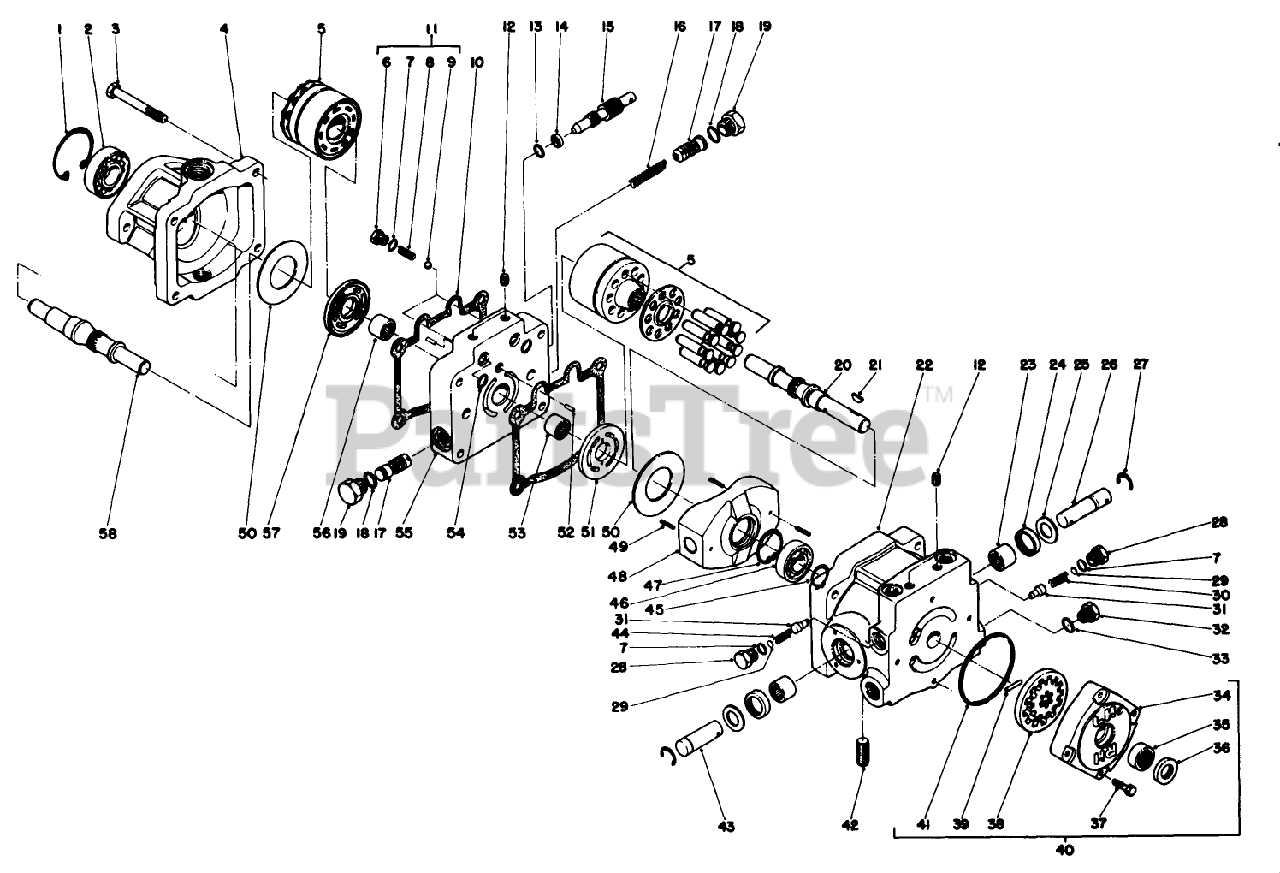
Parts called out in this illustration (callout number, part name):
1	RING-SNAP
2	BEARING
3	SCREW-HH
4	Motor Housing
5	CYLINDER BLOCK KIT
6	PLUG-VALVE, CHECK
7	O-RING
8	SPRING-VALVE
10	GASKET
11	Check Valve Kit (Incl. Ref.#6-9)
12	PLUG-PIPE
13	O-RING
14	RING-BACK UP
15	By Pass Valve
16	SPRING-VALVE
17	VALVE ASM
18	O-RING
19	PLUG-HYD, HH
20	Pump Shaft
21	KEY-WOODRUFF
22	PUMP HSG
23	BEARING-NEEDLE
24	SEAL-LIP
25	WASHER-FLAT
26	SHAFT-TRUNNION
27	RING-RETAINING
28	PLUG-HH
29	PACK-SHIM
30	SPRING-VALVE
31	Cone-Relief Valve
32	PLUG-HH
33	O-RING
34	HOUSING-PUMP, CHARGE
35	NEEDLE BRG
36	SEAL-OIL
37	Screw
38	Gerotor ASM
39	PIN-STRAIGHT, HEADLESS
40	Charge Pump (Incl. Ref.#34-39 & 41)
41	O-RING
42	UNION-FILTER
43	SHAFT-TRUNNION
44	SPRING-VALVE
45	RING-SNAP, EXT
46	BEARING-BALL
47	RING-RETAINING
48	PLATE-SWASH, VARIABLE
49	PIN-SPRING
50	PLATE-THRUST
51	PLATE-VALVE, PUMP
52	PIN-DOWEL
53	BEARING-NEEDLE
54	O-RING
55	Center Section
56	BEARING-SHAFT
57	PLATE-VALVE, MOTOR
58	SHAFT-MOTOR
